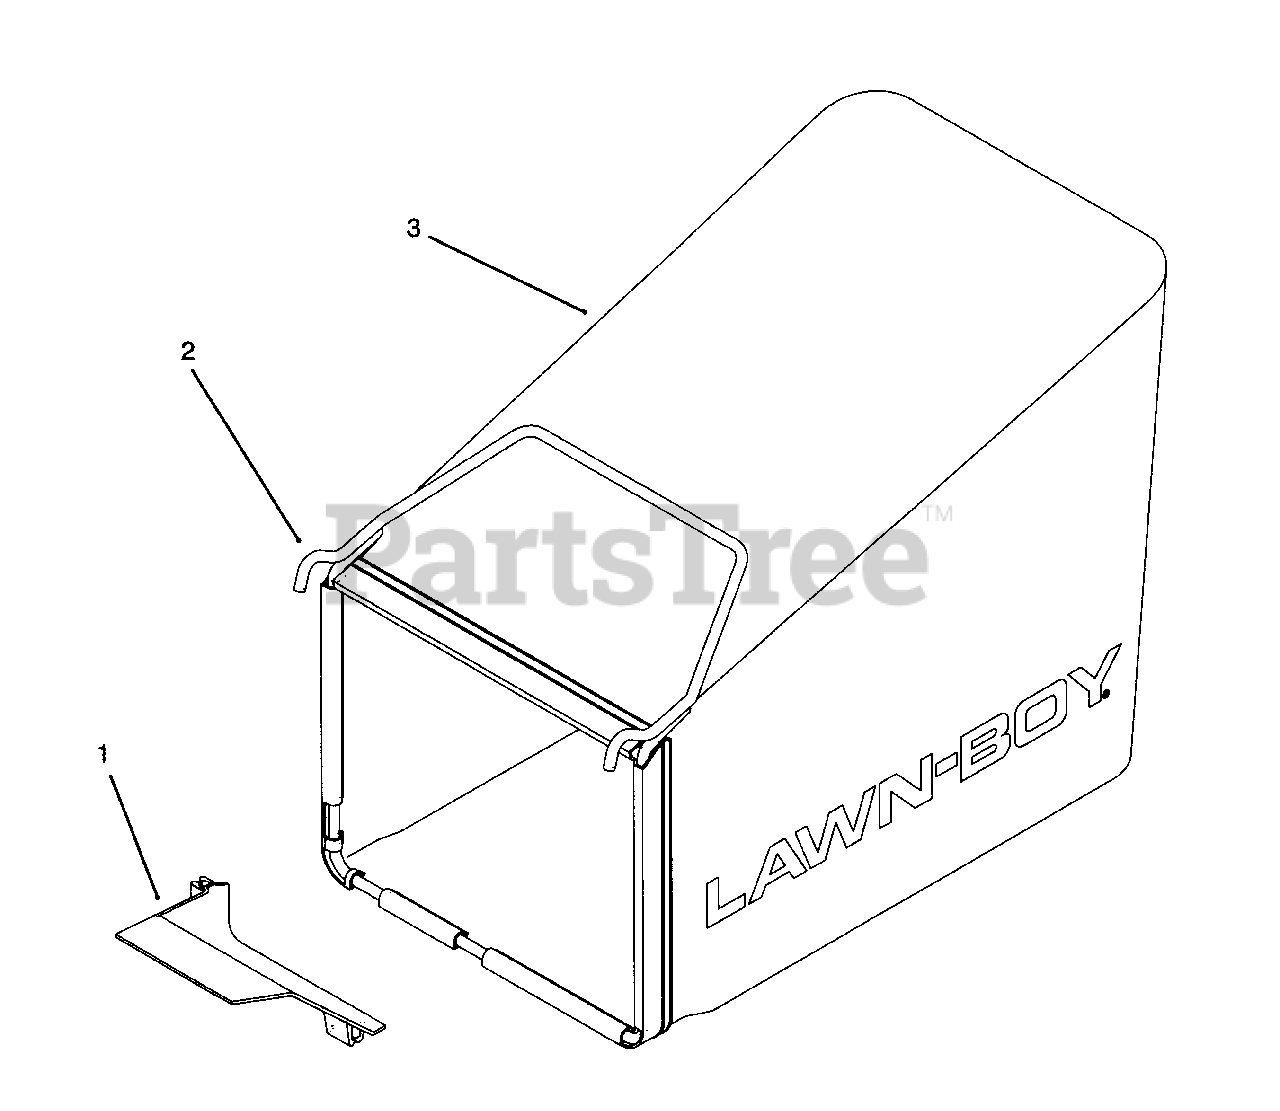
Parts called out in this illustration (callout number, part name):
1	Ramp-Grass Bag
2	Frame
3	Bag-Grass
